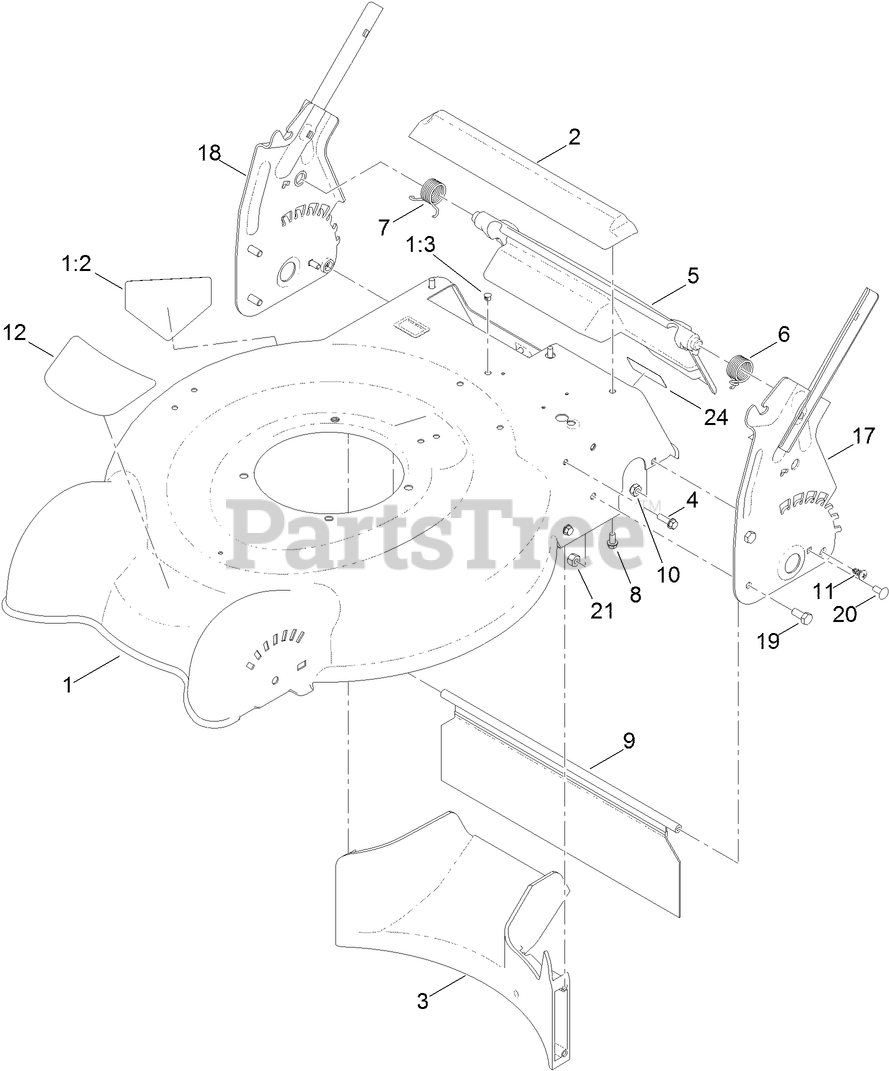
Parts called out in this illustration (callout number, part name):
1	HOUSING ASM
1:2	DECAL-DANGER
1:3	PLUG-DOME
2	CHUTE-REAR
3	BAFFLE-REAR
4	SCREW-HWH
5	REAR DEFLECTOR ASM
6	SPRING-TORSION, LH
7	SPRING-TORSION, RH
8	SCREW-PLASTITE
9	SHIELD-TRAILING
10	NUT-LOCK, NI
11	SCREW-PTH
12	DECAL-DECK
19	SCREW-HH
20	SCREW-CARR
21	NUT-LOCK, NI
24	DECAL-LOCATION, SERVICE DEALER
